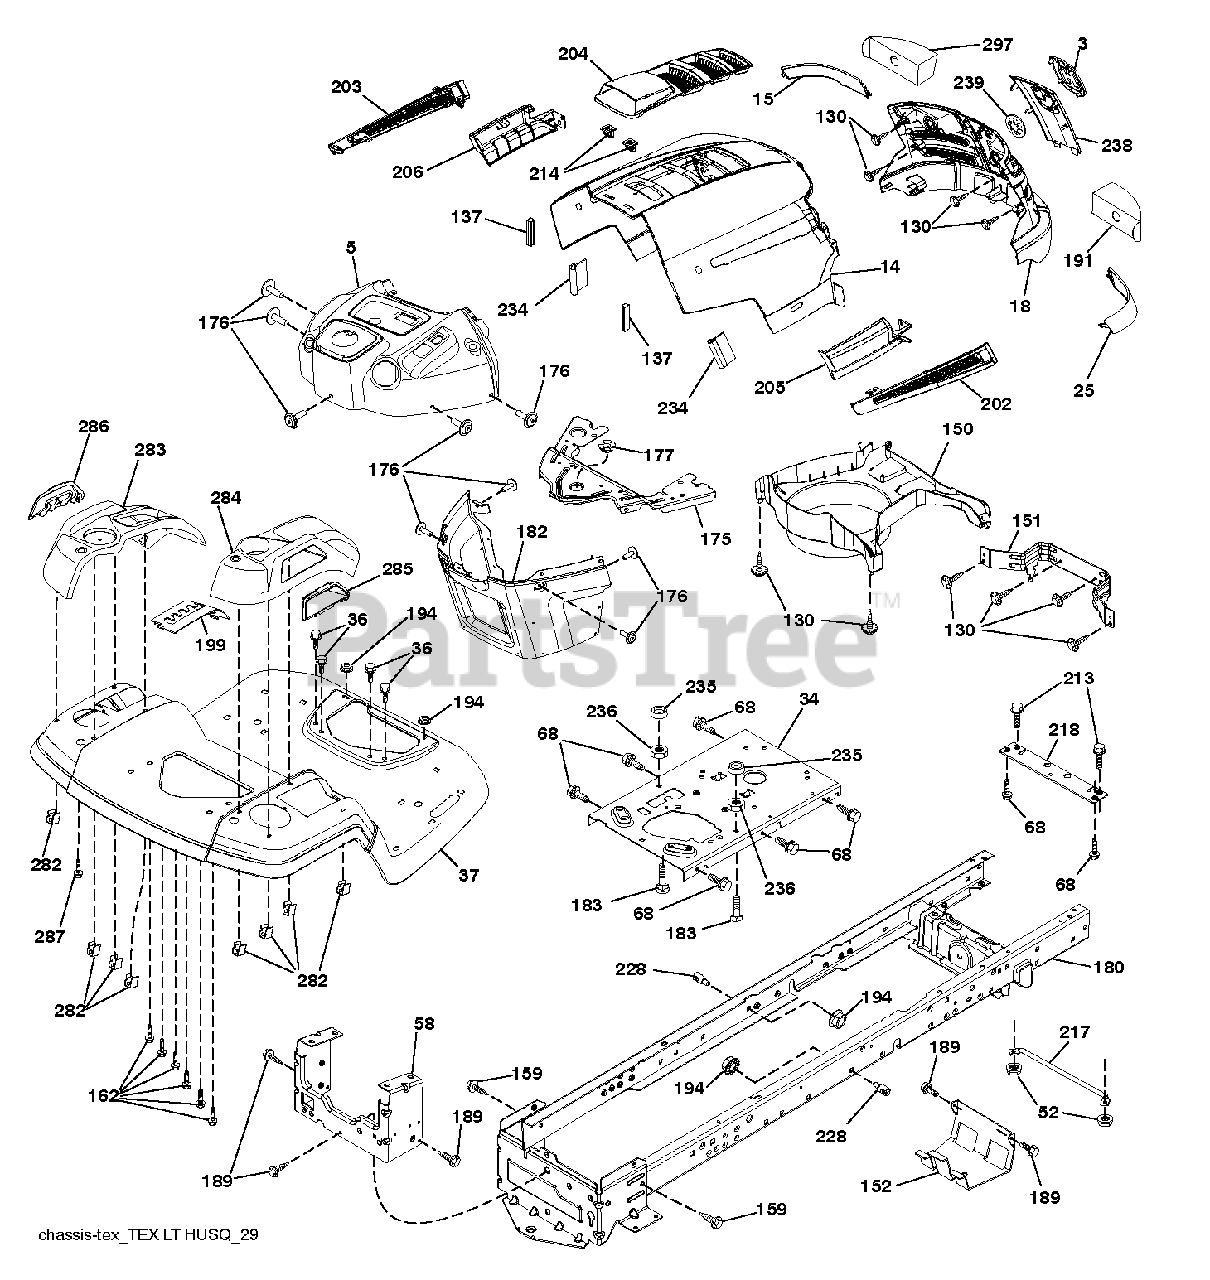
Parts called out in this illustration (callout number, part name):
3	LOGO.HUSQ.GT.LT.CROWN.H
5	SUBASM.DASH.UPPER.HLT.498
14	HOOD.HUSQVARNA.LT.ORANGE
15	LENS.HUSQVARNA LT.RH
18	GRILLE.SVC.HUSQVARNA.GREY
25	LENS.HUSQVARNA LT.RH
34	PLATE PLATE ENGINE
36	SCREW 5/16"
37	FENDER.TLT.FS.W/CUPHLD.ORANGE
52	LOCKNUT
58	DRAWBAR UPPER 2PC SMALL FENDER
68	SCREW LT
130	SCREW.#10 X 0.750.BOS
137	BUMPER DASH
151	BRACKET PIVOT
152	SHIELD.BROWNING.W/TEX
159	SCREW, 3/8-16X3/4
162	SCREW.HI-LO.CONSOLE
175	CROSSMEMBER
176	SCREW.#10-24X5/8.RN.QU
177	BUSHING STEERING
180	CHASSIS.WLDMNT.14GA.2PC.18".TI
182	DASH.LOWER.PREDATOR LT
183	BOLT.5/16-18X1-1/4 FULL THD
189	SCREW
191	INSERT.REFLECTIVE.RH.
194	NUT LOCK HEX FLANGE 5/16-18
199	PLATE.DECK.LIFT.HUSQ.LT
202	VENT.SIDE.HUSQVARNA.LT.RT
203	VENT.SIDE.HUSQVARNA.LT.LFT
204	SUBASM.TOP.VENT.HUSQ.LT
205	SKIRT.SIDE.HUSQVARNA.LT.RT
206	SKIRT.SIDE.HUSQVARNA.LT.LEFT
213	BOLT
214	CLIP.RETAINER.TINNER.
217	ROD.PIVOT.HOOD
218	X-PIECE.HOOD.STOP.NON/
228	STUD.FASTNER.W/ANTI-ROTATE
234	BUMPER.HOOD.TEX.HUSQVARNA
235	SPACER FENDER
236	NUT.CENTERLOCK.5/16-
238	TRIM.HUSQ LT.668
282	CLIP.RETAINER.CONSOLE.LT.HUSQ
283	CONCOLE.CNTRL.PDL.HUSQ.LT.498
284	CONSOLE.ASM.LFT.RSF.HUSQ.LT
285	CONSOLE.INSRT.LH.HUSQ.LT.BLACK
286	CONSOLE INSERT RH
287	SCREW 1/4X20
297	INSERT REFLECTIVE
